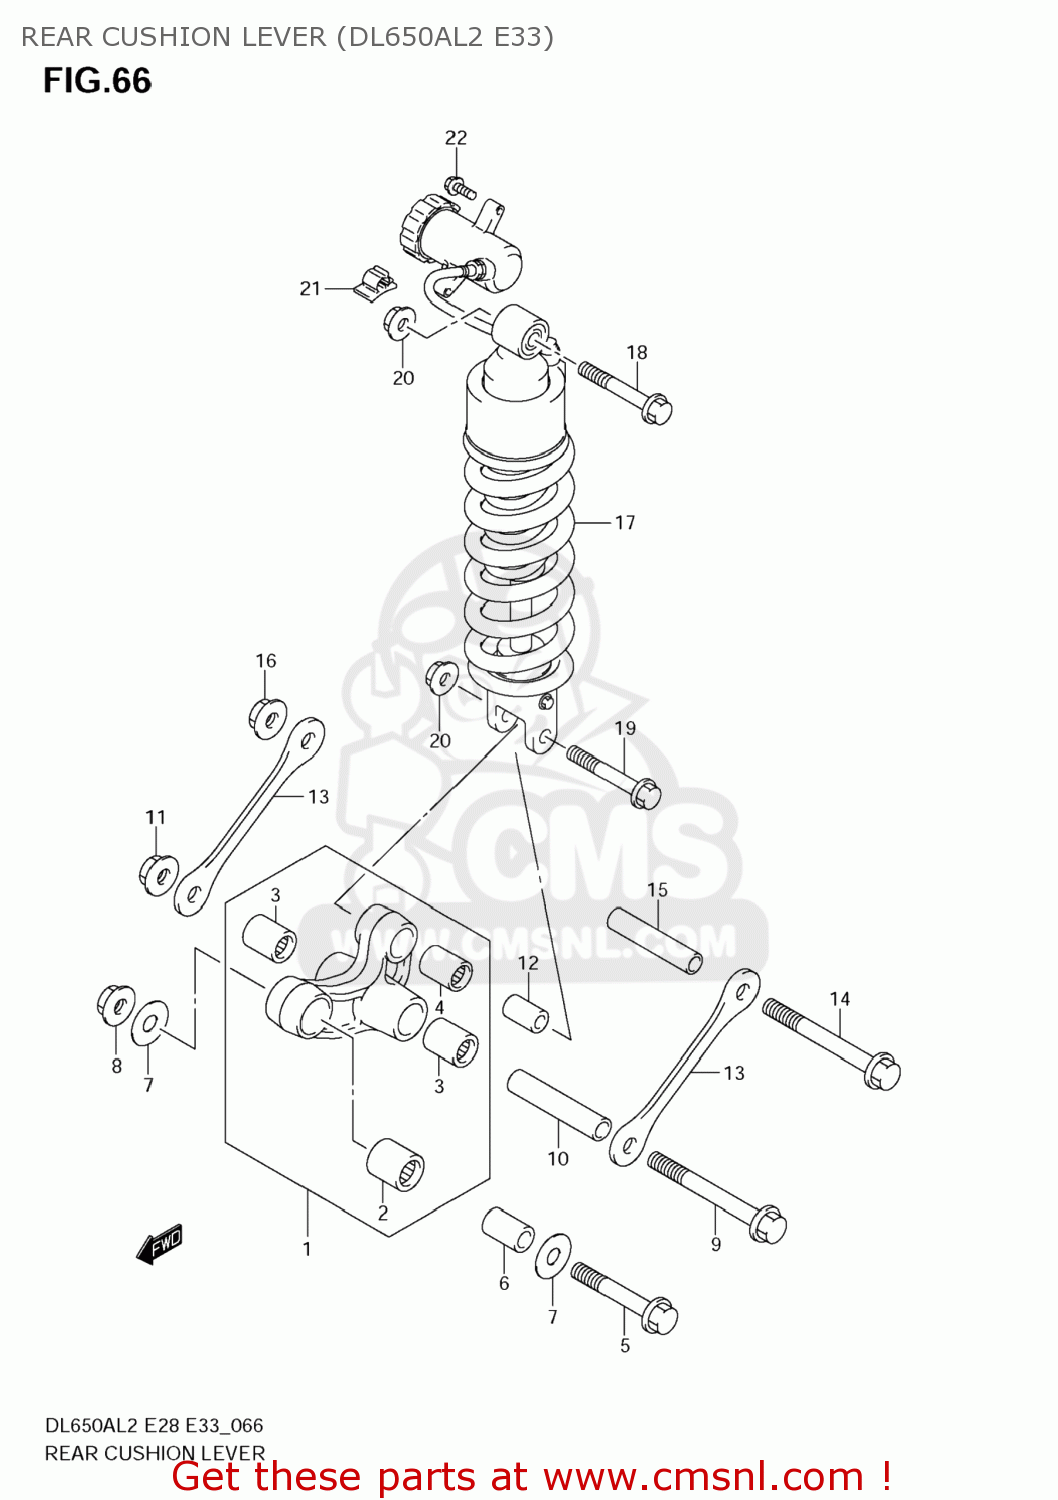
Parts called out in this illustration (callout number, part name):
1	LEVER SET,RR CUSHION
2	BEARING(20X27X30)
3	BEARING(17X24X25)
4	BEARING(17X24X26)
5	BOLT,RR CUSHION LEVER FR
6	SPACER,RR CUSHION LEVER FR
7	WASHER(12X34X1)
8	NUT
9	BOLT,RR CUSHION ROD
10	SPACER(12X17X85)
11	NUT
12	SPACER,RR CUSHION LEVER
13	ROD,RR CUSHION LEVER
14	BOLT,RR CUSHION ROD
15	SPACER(12X17X85)
16	NUT
17	ABSORBER ASSY,RR SHOCK
18	BOLT(10X70)
19	BOLT(10X55)
20	NUT
21	CLAMP
22	BOLT
